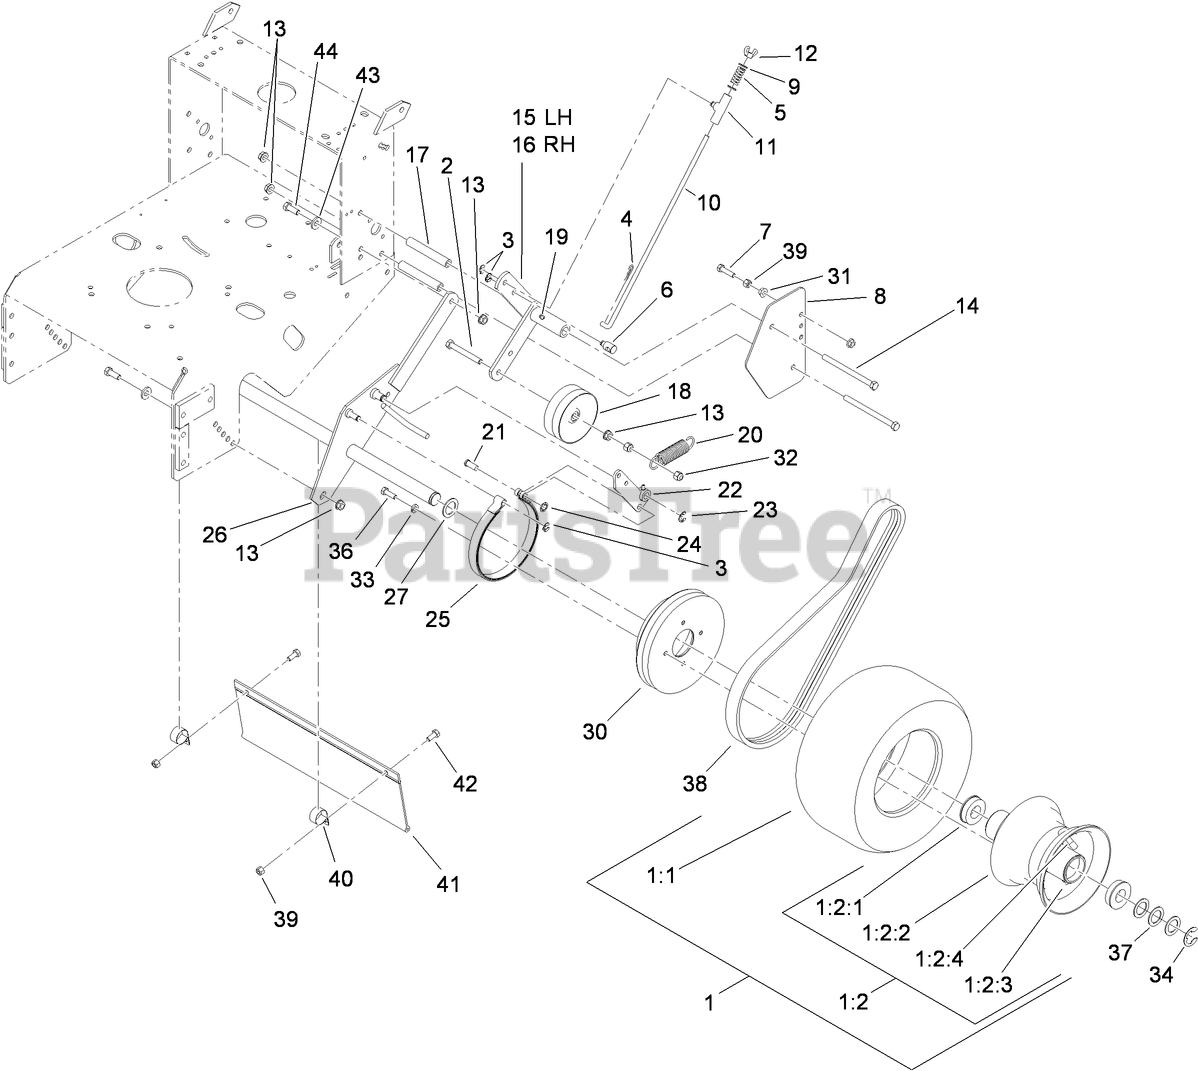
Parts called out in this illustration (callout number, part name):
1	Wheel and Tire ASM
1:1	Tire-Turfmaster
1:2	WHEEL AND HUB ASM
1:2:1	BEARING-FLANGED
1:2:2	Rim ASM
1:2:3	Fitting-Grease
1:2:4	Stem-Valve
2	SCREW-HH
3	RING-RETAINING
4	PIN-COTTER
5	SPRING-COMPRESSION
6	Swivel-Lever, Drive
7	SCREW-HH, SPECIAL
8	Shield-Wheel, Drive
9	WASHER-PLAIN
10	Linkage-Brake
11	SWIVEL-BRAKE
12	WINGNUT-NYLOCK
13	NUT-HHF, WHIZ
14	SCREW-HH
15	Arm-Idler, LH
16	Arm-Idler, RH
17	SPACER-SHIELD
18	PULLEY-IDLER
19	FITTING-GREASE
20	SPRING-EXTENSION
21	PIN-CLEVIS
22	ARM-BRAKE
23	RING-RETAINING, EXTERNAL
24	NUT-PUSH
25	BAND-BRAKE
27	WASHER-SPACER
30	DRUM AND SHEAVE ASM
31	NUT-HF
32	NUT-LOCK, NI
33	WASHER-LOCK
34	RING-SNAP
36	SCREW-HH
37	WASHER-SPACER
38	V-BELT
39	NUT-LOCK, NI
40	CLAMP-R
41	SHIELD-TRAILING
42	SCREW-HH
43	WASHER-BELLEVILLE
44	SCREW-HH
